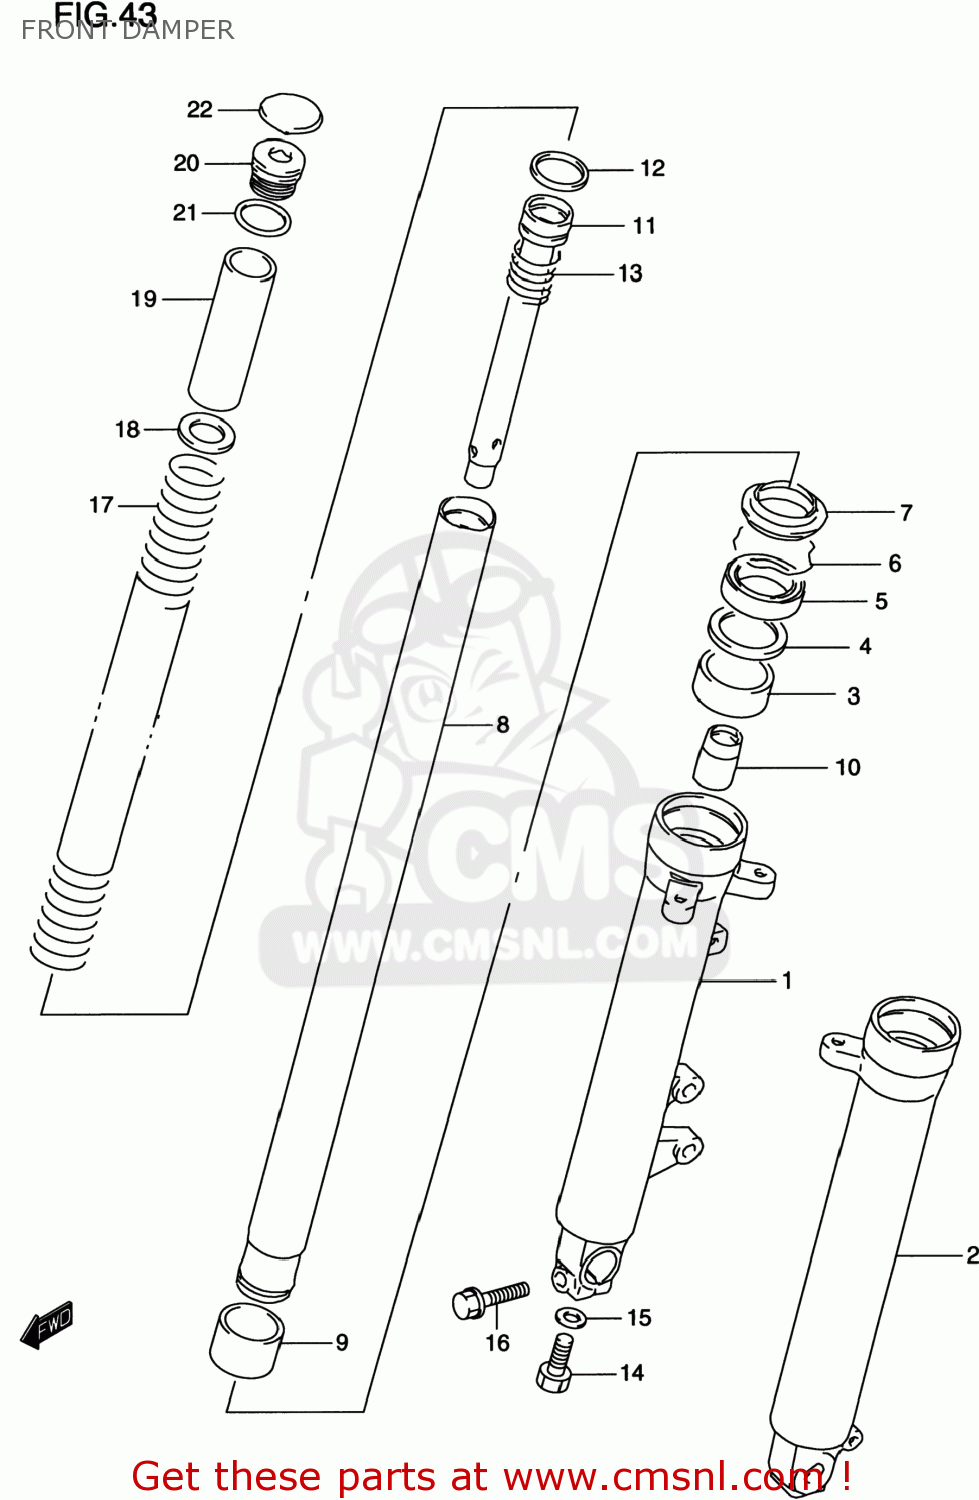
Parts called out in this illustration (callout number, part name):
1	TUBE,OUTER,RIGHT (SILVER)
2	TUBE,OUTER,R
3	METAL,SLIDE
4	WASHER
5	SEAL,OIL
6	RING,STOPPER
7	SEAL,DUST
8	TUBE,INNER
9	PISTON
10	PIECE,OIL LOCK
11	CYLINDER
12	RING,PISTON
13	SPRING,REBOUND
14	BOLT,FORK CYLINDER(10X25)
15	GASKET (NAS)
16	BOLT
17	SPRING
18	WASHER
19	SPACER
20	BOLT,FORK
21	O RING
22	CAP,FR FORK
